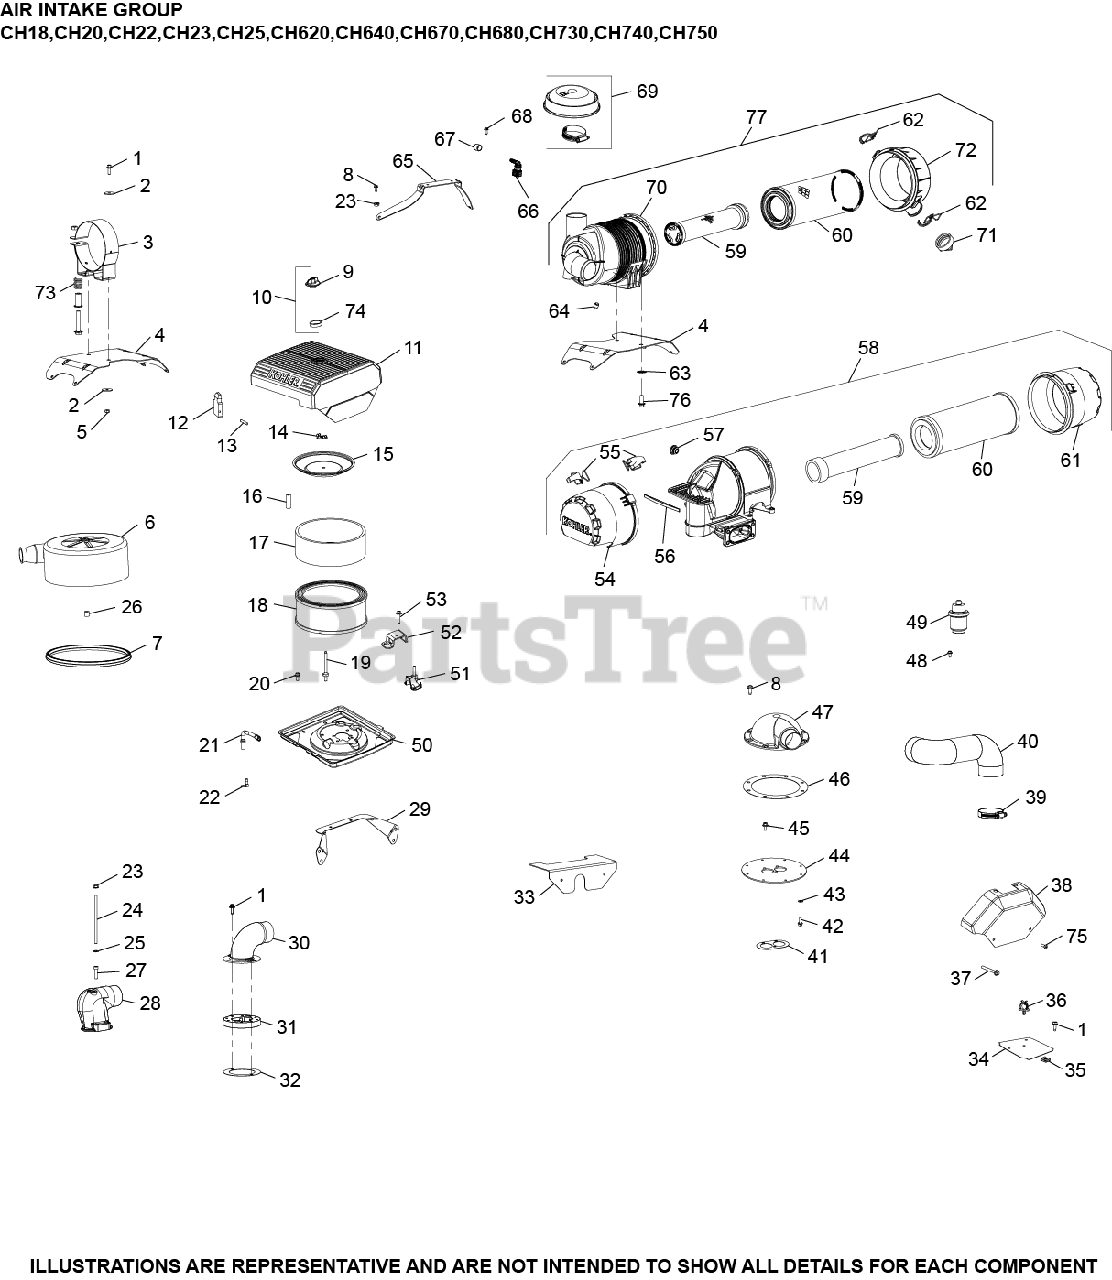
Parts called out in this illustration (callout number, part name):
1	SCREW, THREAD FORMING
21	HOSE, EVAP
22	CONNECTOR, EVAPORATIVE HOSE
33	SHIELD, DEBRIS
42	SCREW, HVY FLG M5X.8X16
44	KIT, PLATE ADAPTER
46	GASKET, AIR CLEANER ADAPTER
47	ADAPTER, AIR INTAKE
